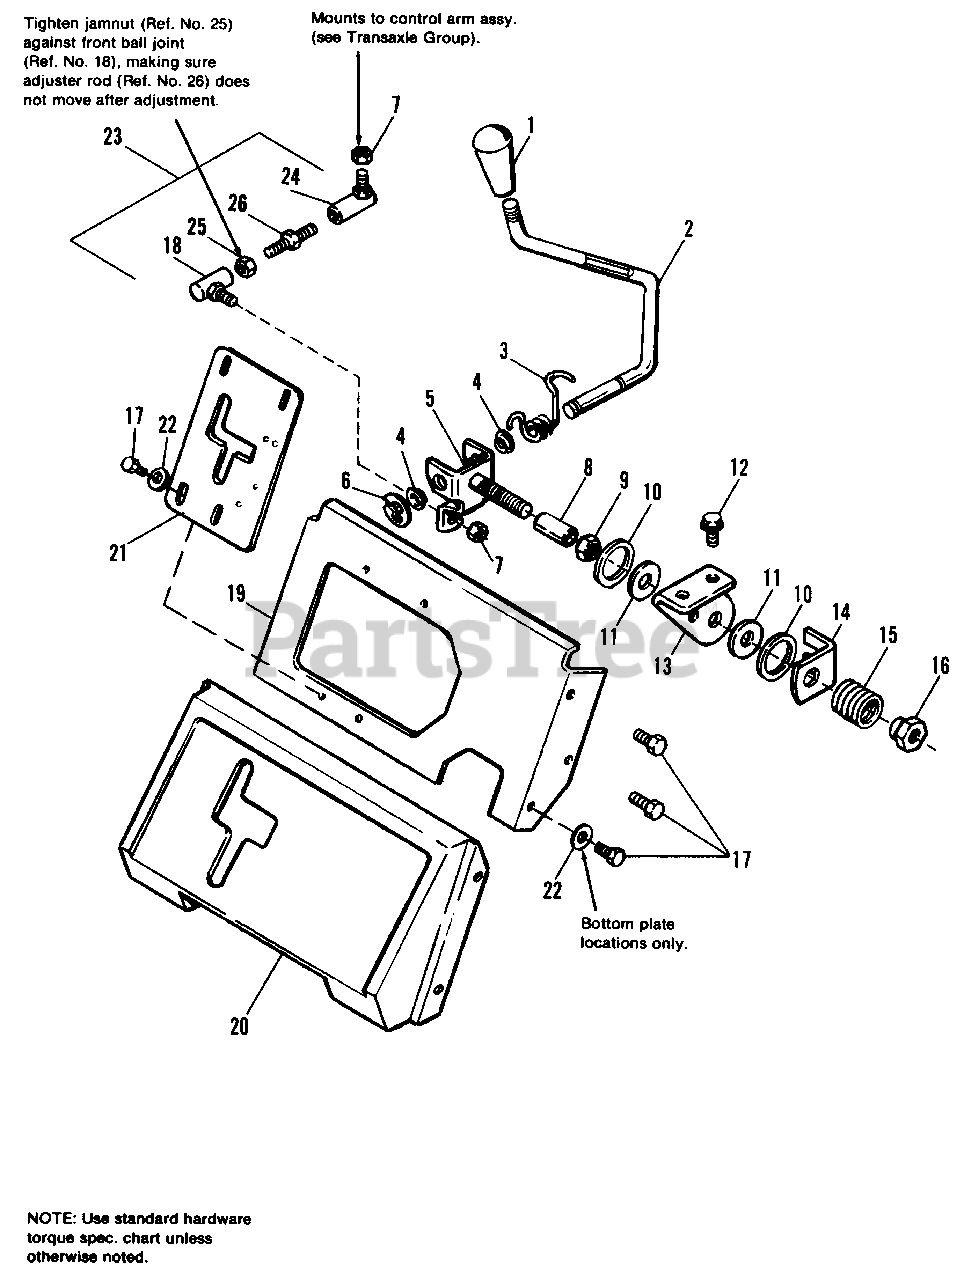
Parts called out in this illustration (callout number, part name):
1	HANDLE, Speed Control
3	SPRING, Torsion
5	BRACKET ASSY., Speed Control
6	E-RING
7	NUT, Centerlock, 3/8-24
9	NUT, Hex Lock, 3/8-16
10	RING, Containment
11	DISC, Friction
12	SCREW, Taptite, 5/16-18 x 5/8
13	BRACKET, Speed Control Support
14	BRACKET, Pivot
15	SPRING, Compression
16	NUT, Spacer
17	SCREW, Taptite, 1/4-20 x 1/2
18	BALL JOINT, L.H. Thrd.
19	PLATE, Quadrant Mounting
20	PANEL, Shift
21	QUADRANT, Speed Control
22	WASHER, 1/4
23	BALL JOINT ASSY., (Incl. Ref. Nos. 18, 24, 25 & 26)
24	BALL JOINT, R.H. Thrd.
25	JAM NUT, 3/8-24
26	ADJUSTER ROD
